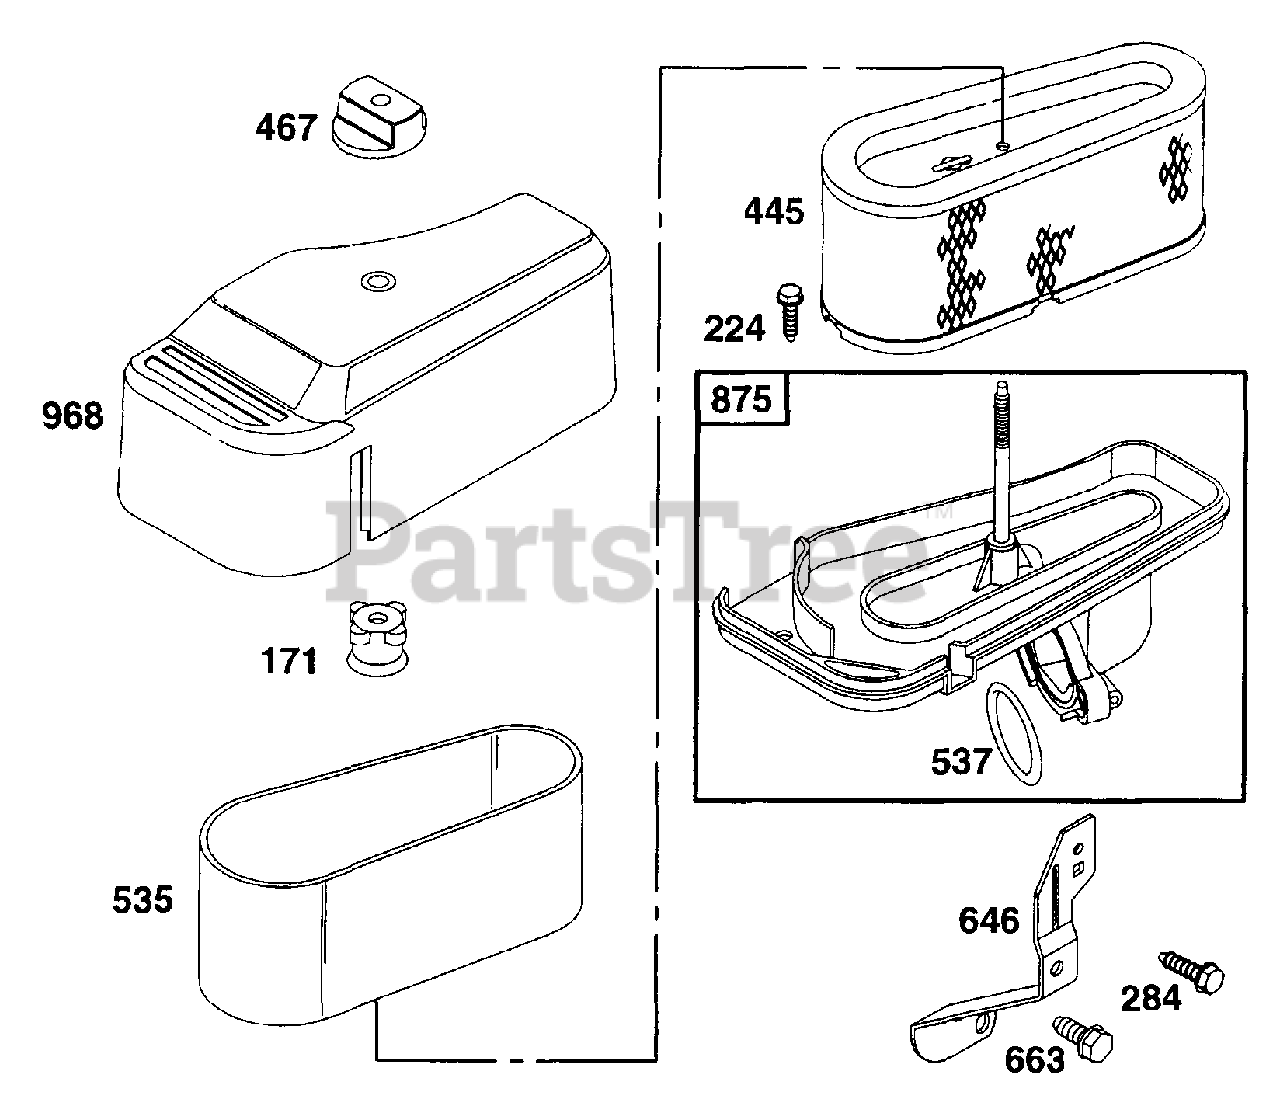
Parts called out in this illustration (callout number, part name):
171	Air Cleaner Knob
224	Hex Screw
284	Hex Screw
445	A/C Cartridge Filter
467	Air Cleaner Knob
535	Pre-Cleaner Filter
537	Seal-O-Ring
646	Support Bracket
663	Hex Screw
875	A/C Plastic Base
968	Air Cleaner Cover
